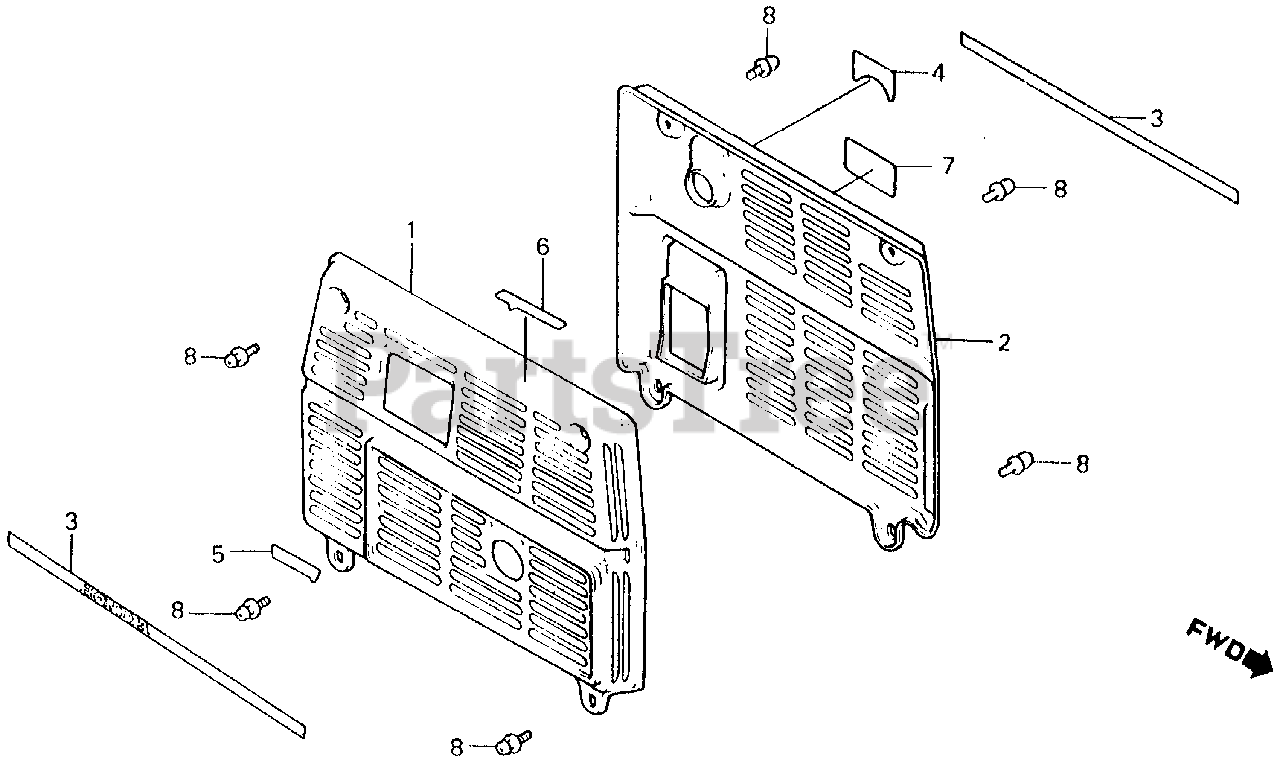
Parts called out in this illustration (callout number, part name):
1	COVER, L. SIDE *YR108CS* (CANDY FLASH ORANGE-S) (NOT AVAILABLE)
2	COVER, R. SIDE *YR108CS* (CANDY FLASH ORANGE-S) (NOT AVAILABLE)
4	MARK, THROTTLE
5	MARK, TOOL (NOT AVAILABLE)
6	MARK, EX. CAUTION
7	MARK, OIL CHECK (NOT AVAILABLE)
8	SCREW-WASHER (5X10)
